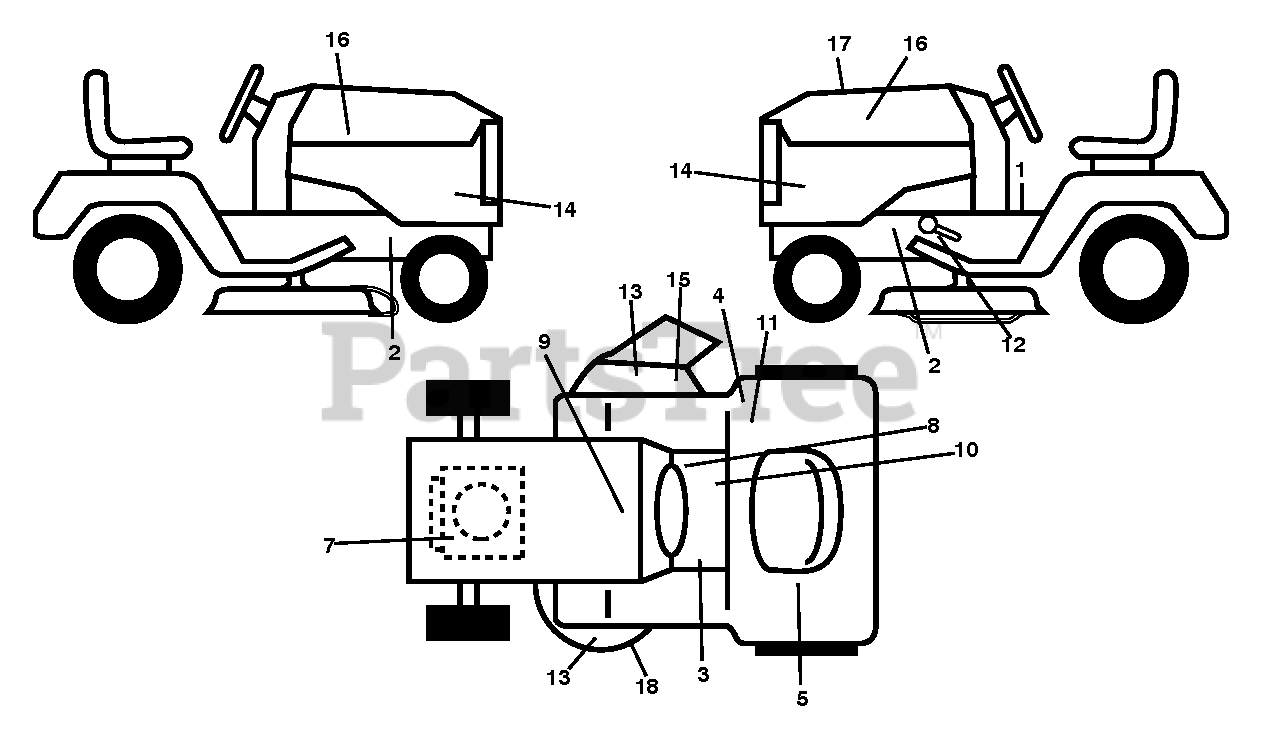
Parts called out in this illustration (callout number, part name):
1	DECAL.READ.OWN.MAN.SYMBOL.LT
2	DECAL.CHASSIS.HOT.MUFFLER
3	DECAL.FNDR.SDLE.BRAKE.CLUTCH.6
4	DECAL.80.DBA.AUSTRALIA
5	DECAL.WARN.FUEL.RESERVE
7	DECAL.ENGINE.WARNING
8	DECAL.PARKING.BRAKE.SADDLE.LT
9	DECAL BTRY SYMBOLS
10	DECAL.PEDALS.SYMBOL
11	DECAL.TICKMARK.6MIL.AUSTRALIA
12	DECAL.PEDAL.HUSQ.CROWN
13	DECAL.DECK.6MIL.EURO.NOSTEP
14	DECAL.SDPNL.GT2.SET.GTH3052TDF
15	DECAL.DECK.6MIL./DEF.SHLD.WARN
16	DECAL.BADGE.170MM.TEXTLOGO.
18	DECAL.MOWER.SCH.48/54.PREM
